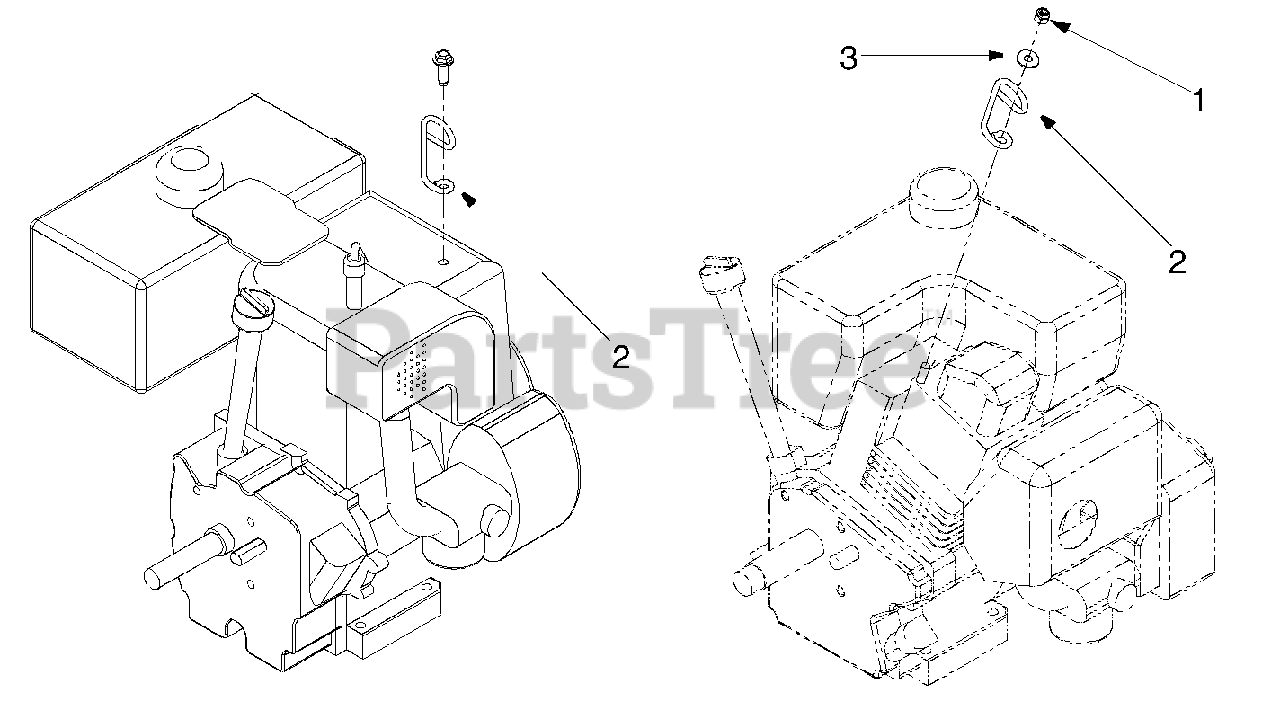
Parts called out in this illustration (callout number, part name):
1	Hex Lock Nut: 1/4-20
2	Cable Guide
3	Flat Washer
